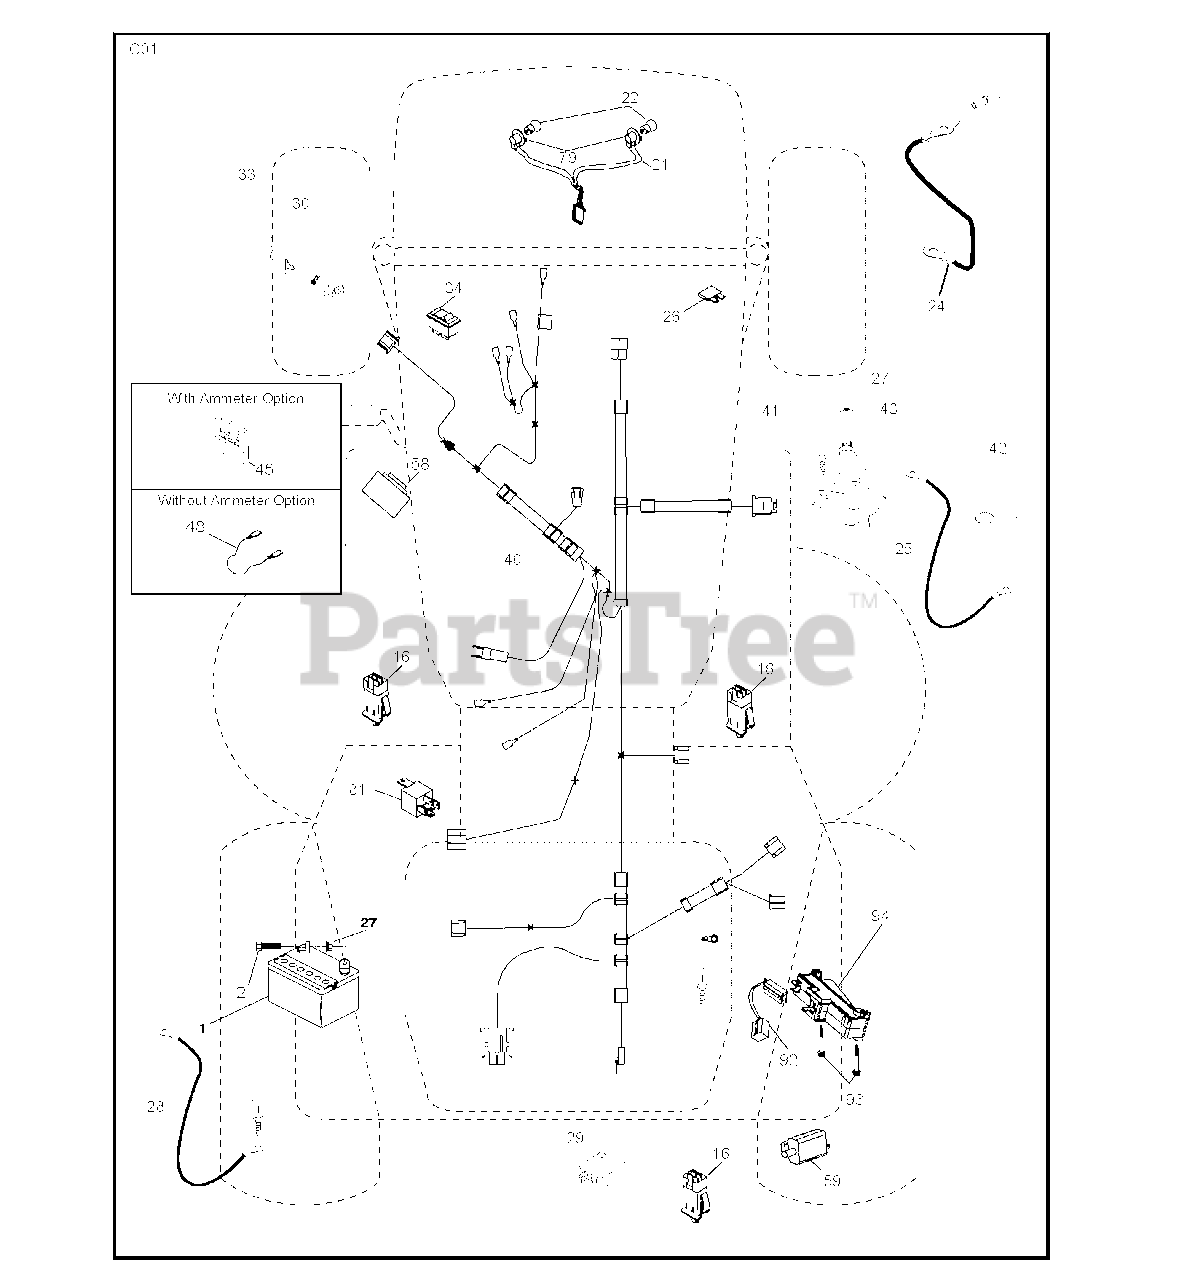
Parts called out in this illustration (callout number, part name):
1	REPL BY 532 12 38-99
16	SWITCH INTERLOOK PUSH-IN
21	HARNESS ASSY LIGHT
22	LIGHTBULB
24	BATTERY CABLE GT
25	CABLE BATTERY
26	FUSE 20AMP
27	NUT
28	CABLE GROUND
29	SWITCH.SEAT.DP W/RAMPS
30	SWITCH.IGN.DELTA.W.LGH.ROS
33	KEY.CHAIN.BLISTER.PACK.GEN.INT
34	SWITCH LT
42	TERMINAL COVER
43	SOLENOID.W/BRASS.PLUNG
58	BUZZER
66	SCREW LT
79	BULB HOLDER ASM.
81	RELAY.ASSY.T
92	HARNESS.PIGTAIL.CONSLE
93	SCREW.PLASTITE
94	MODULE.REVERSE.ROS
